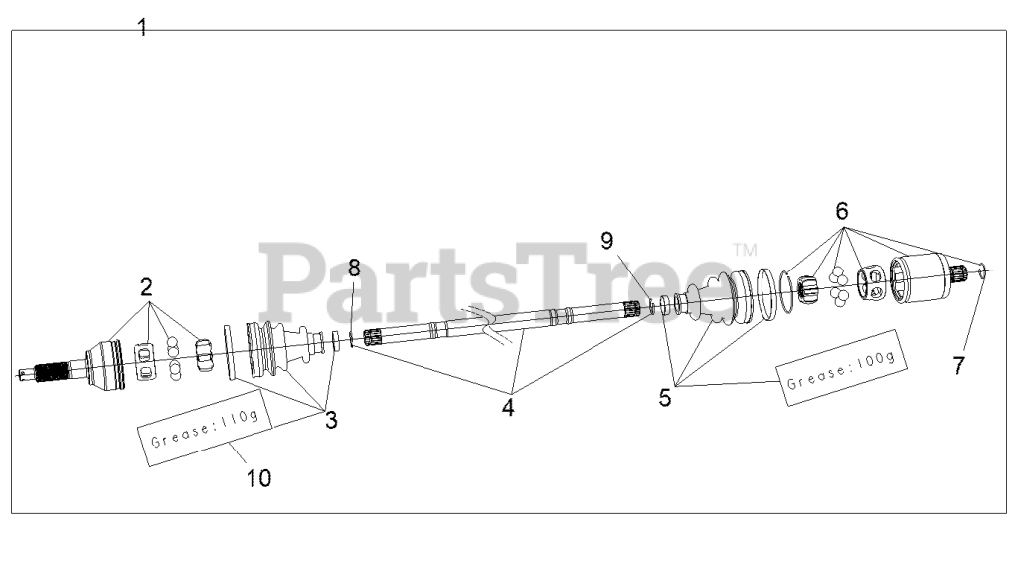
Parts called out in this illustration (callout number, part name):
1	ASM-HALFSHAFT-REAR
2	JOINT OUTER
3	KIT-BOOT(PR-8071)
4	BAR
5	K-BOOT- INNER
6	JOINT- INNER
10	GREASE(K575/VW738)
